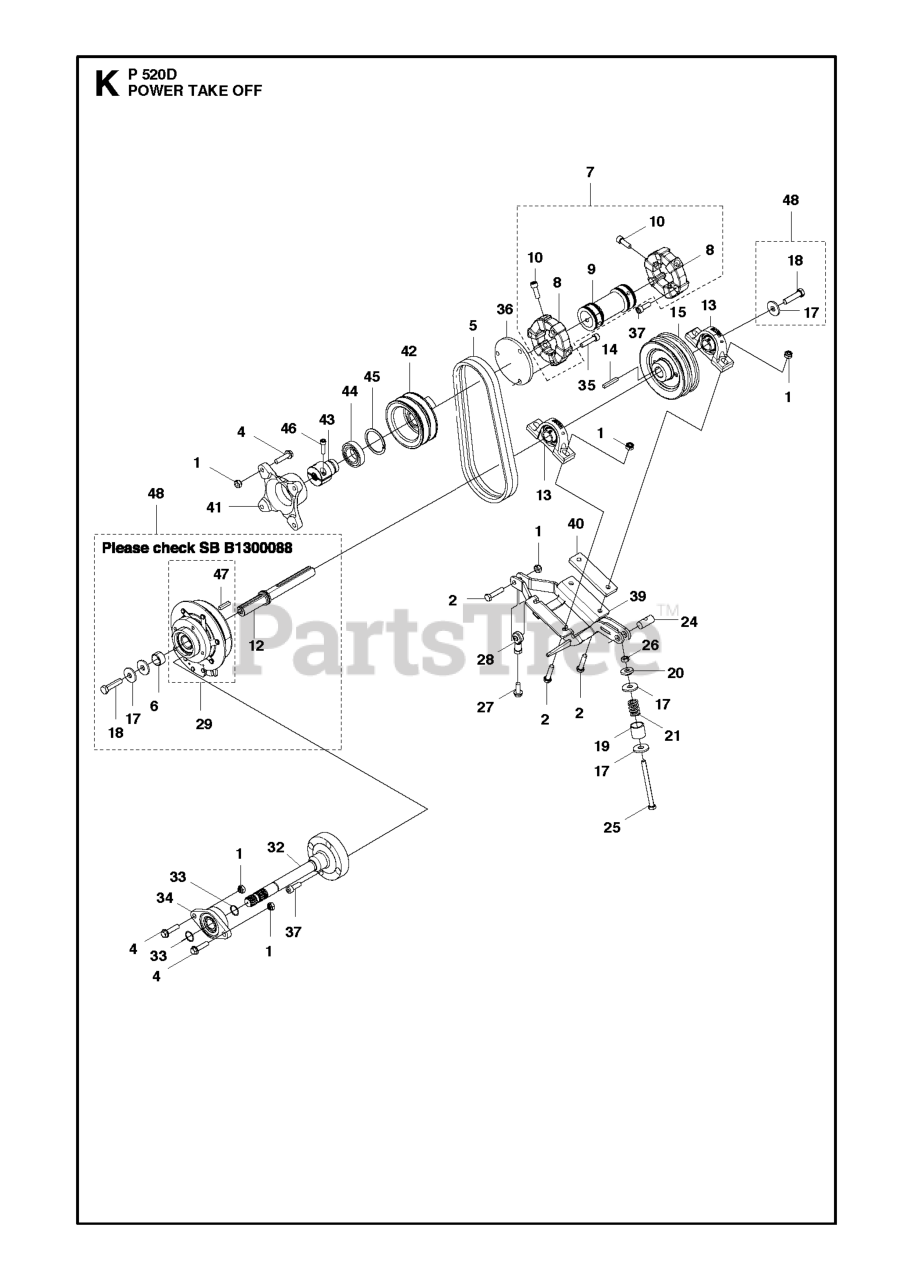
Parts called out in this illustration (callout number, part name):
2	SCREW IHSCM M10X45 12.9 ZPB L
26	NUT
34	BEARING UNIT FYTB 25TF
35	SCREW IHSCM M10X45 12.9 ZPB L
37	SCREW IHSCM M10X30 12.9 ZPB L
